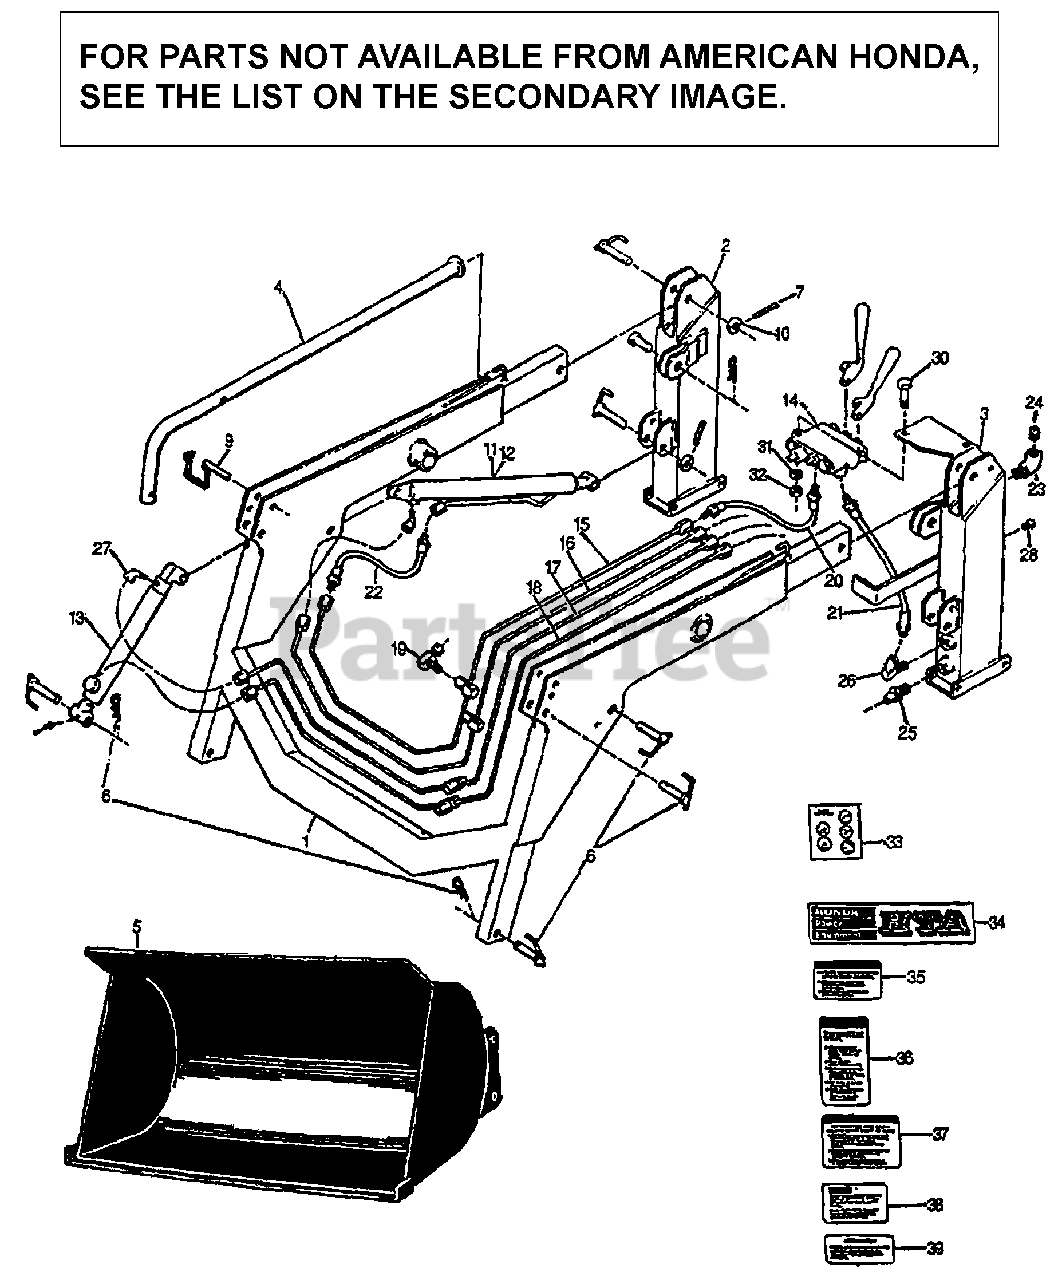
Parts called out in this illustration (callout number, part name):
8	PIN, CLIP (#11)
9	PIN, LYNCH (3/8X2 1/4")
10	BUSHING (1 1/4X3/4")
15	FEEDLINE (UPPER)
16	FEEDLINE (BND)
17	FEEDLINE (3RD)
18	FEEDLINE (LOWER)
19	NUT, SWIVEL (9/16-18) (90 ELBOW)
20	HOSE, HYDRAULIC (1/4X24")
21	HOSE, HYDRAULIC (3/8X20")
22	HOSE, HYDRAULIC (1/4X16")
24	PLUG, VENT (1/2")
25	PIPE END (1/2")
28	SCREW, SELF-TAPPING HEX. (10X1/2")
29	GREASE FITTING (1/4-20X2")
40	DECAL KIT
NI	SEAL KIT, CYLINDER
